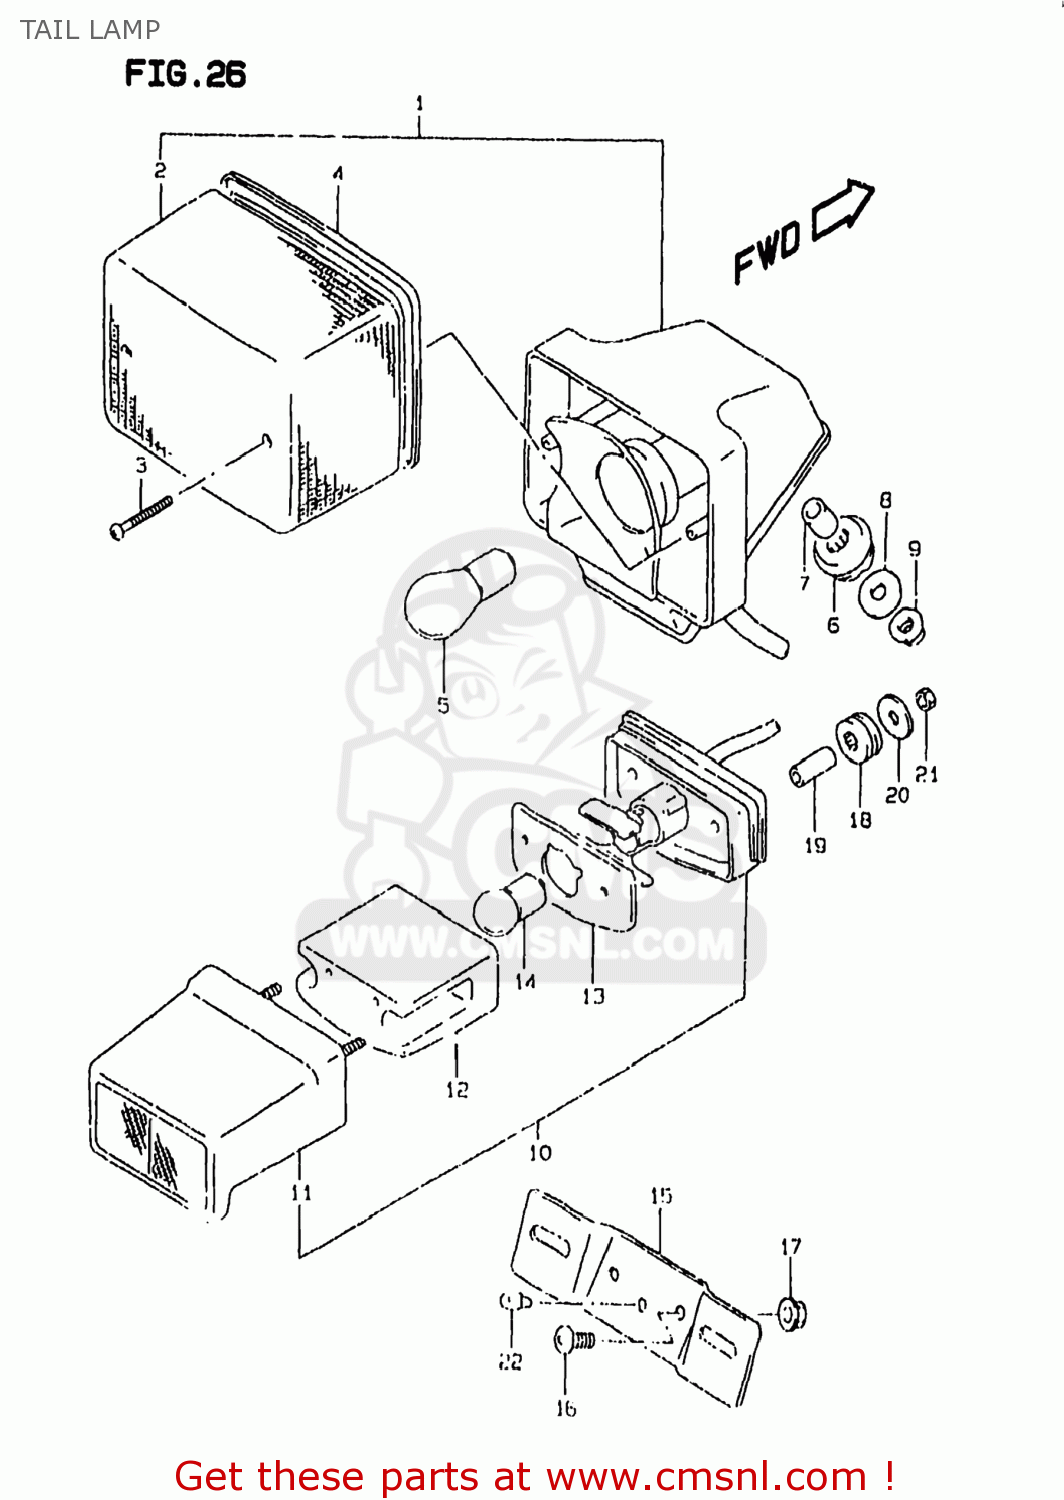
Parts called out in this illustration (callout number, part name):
1	LAMP ASSY,RR COMBINATION
2	LENS,TAIL LAMP
3	SCREW(4X45)
4	GASKET,LENS (NAS)
5	BULB(12V21/5W)
6	CUSHION
7	SPACER(6.5X9X9)
8	WASHER(6.5X20X1.6)
9	NUT 6MM
10	LAMP ASSY,LICENSE
11	REFLECTOR/COVER
12	LENS
13	GASKET,LICENSE LAMP (NAS)
14	BULB(12V5W,BF150-40160A)
15	BRACKET,LICENSE PLATE
16	SCREW
17	NUT
18	CUSHION
19	SPACER(5.5X9.5X28.5)
20	WASHER(5.5X20X1.2)
21	NUT
22	CUSHION
